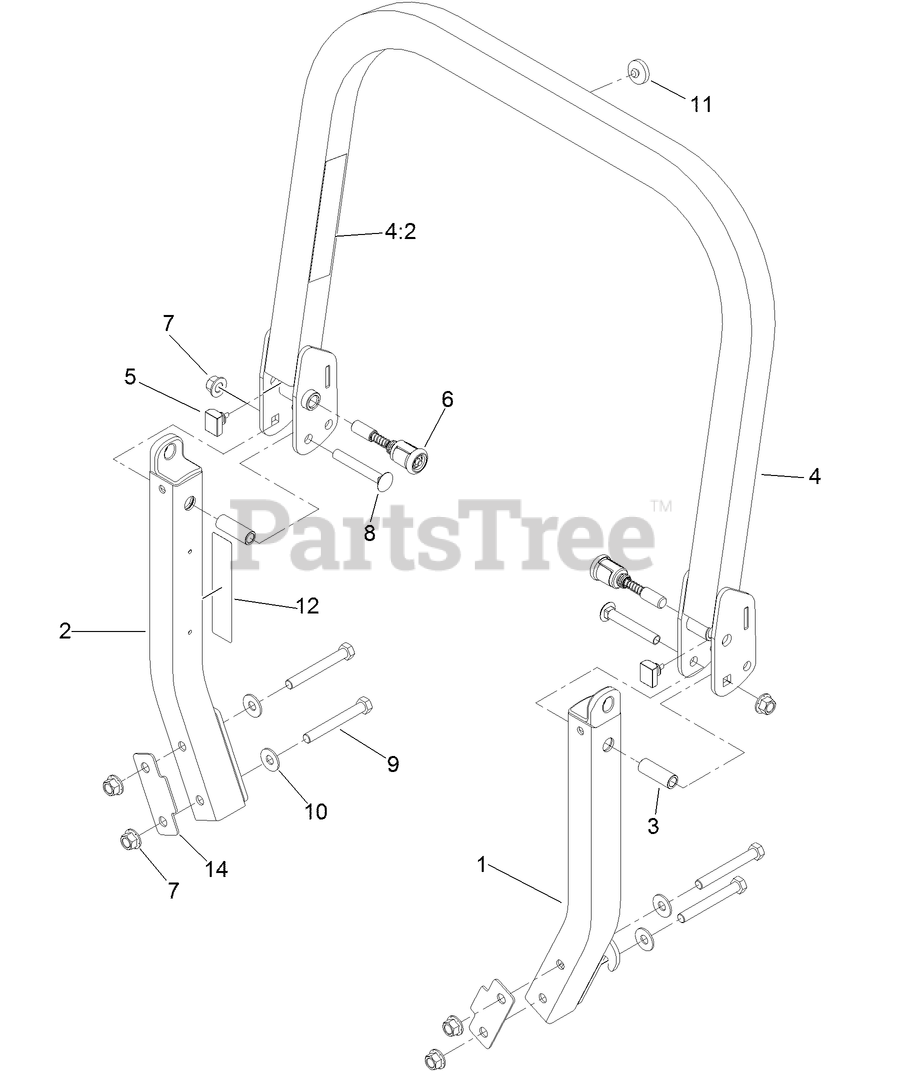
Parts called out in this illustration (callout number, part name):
1	LEG-ROPS, LH
2	LEG-ROPS, RH
3	SPACER
4	UPPER ROPS ASM
4:2	DECAL-WARNING
5	BUMPER-ROPS
6	PIN-SPRING
7	NUT-LOCK
8	SCREW-CARR
9	SCREW-HH
10	WASHER-SPRING
11	BUMPER-PUSH-IN, RUBBER
12	DECAL-CAUTION, FUEL VENT
14	SPACER
